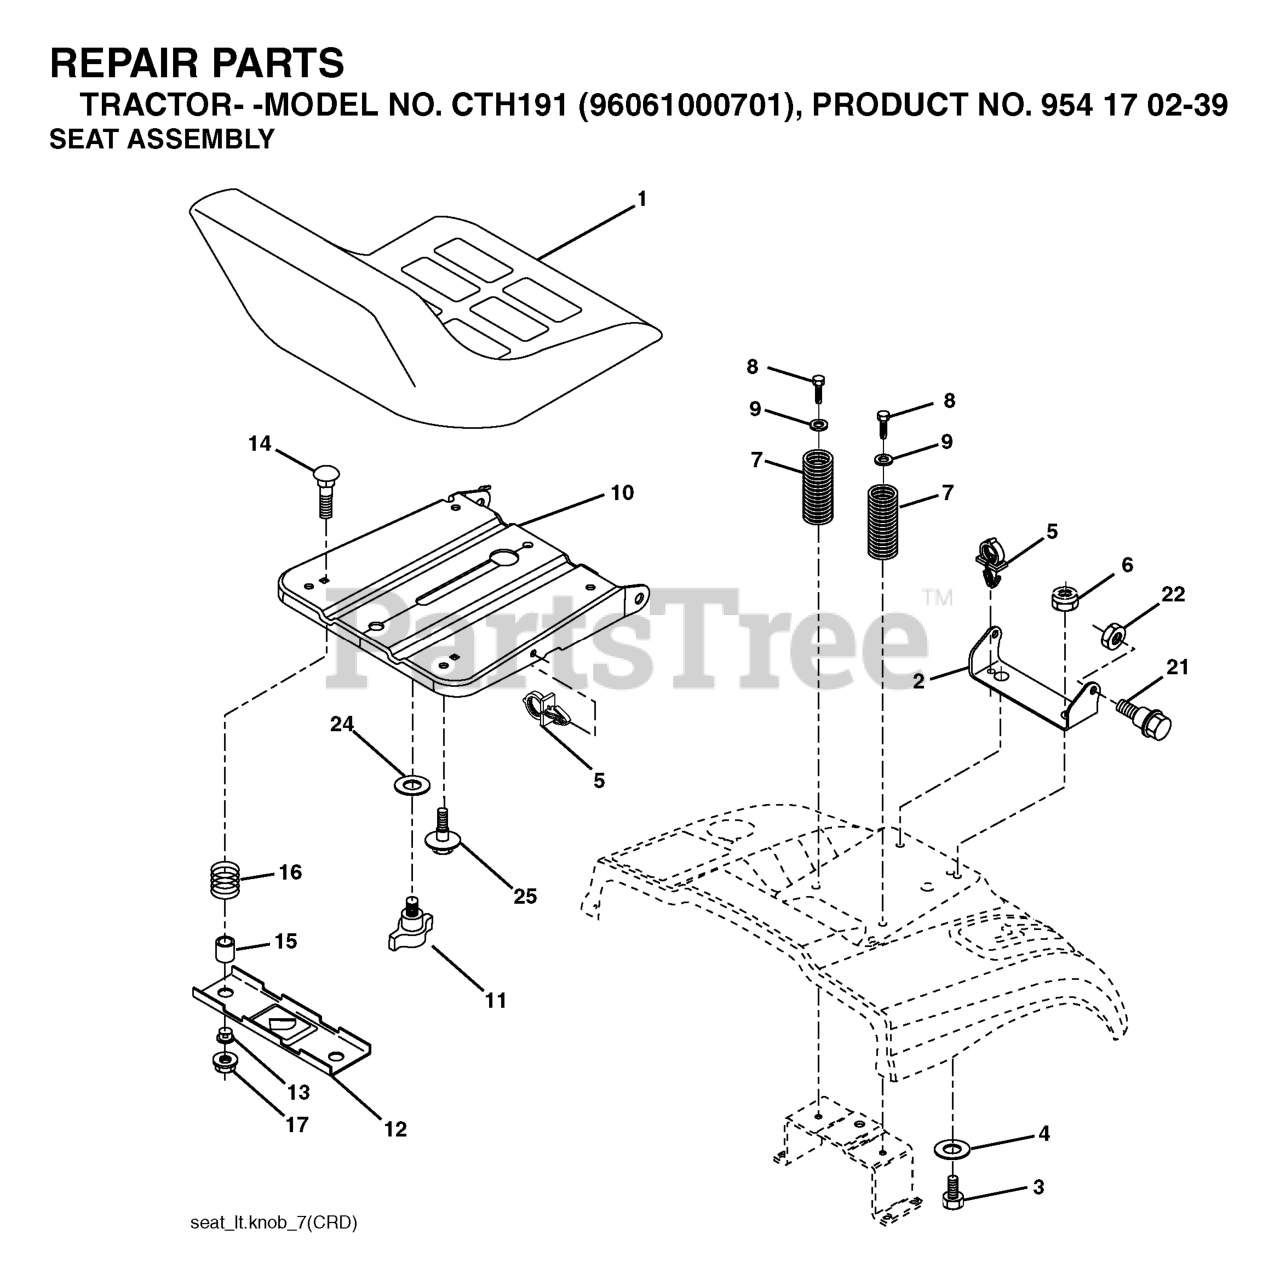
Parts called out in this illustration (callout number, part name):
1	SEAT
2	SEAT PIVOT BRKT
3	BOLT, HEX 3/8-16X1
6	NUT
7	SPRING COMPRESSION
8	SCREW 3/8-16X1
9	WASHER
10	PAN SEAT
11	KNOB.SEAT.ADJ.WINGNUT
12	BRKT SWITCH
14	BOLT.ROUND.HEAD.SQUARE.NECK
15	SPACER SPLIT
16	SPRING COMPRESSED
17	NUT T
21	BOLT.SHOULDER.5/16-18
22	NUT.71038.31-18.HEX.NYLOCK
25	BOLT,SHOULD
